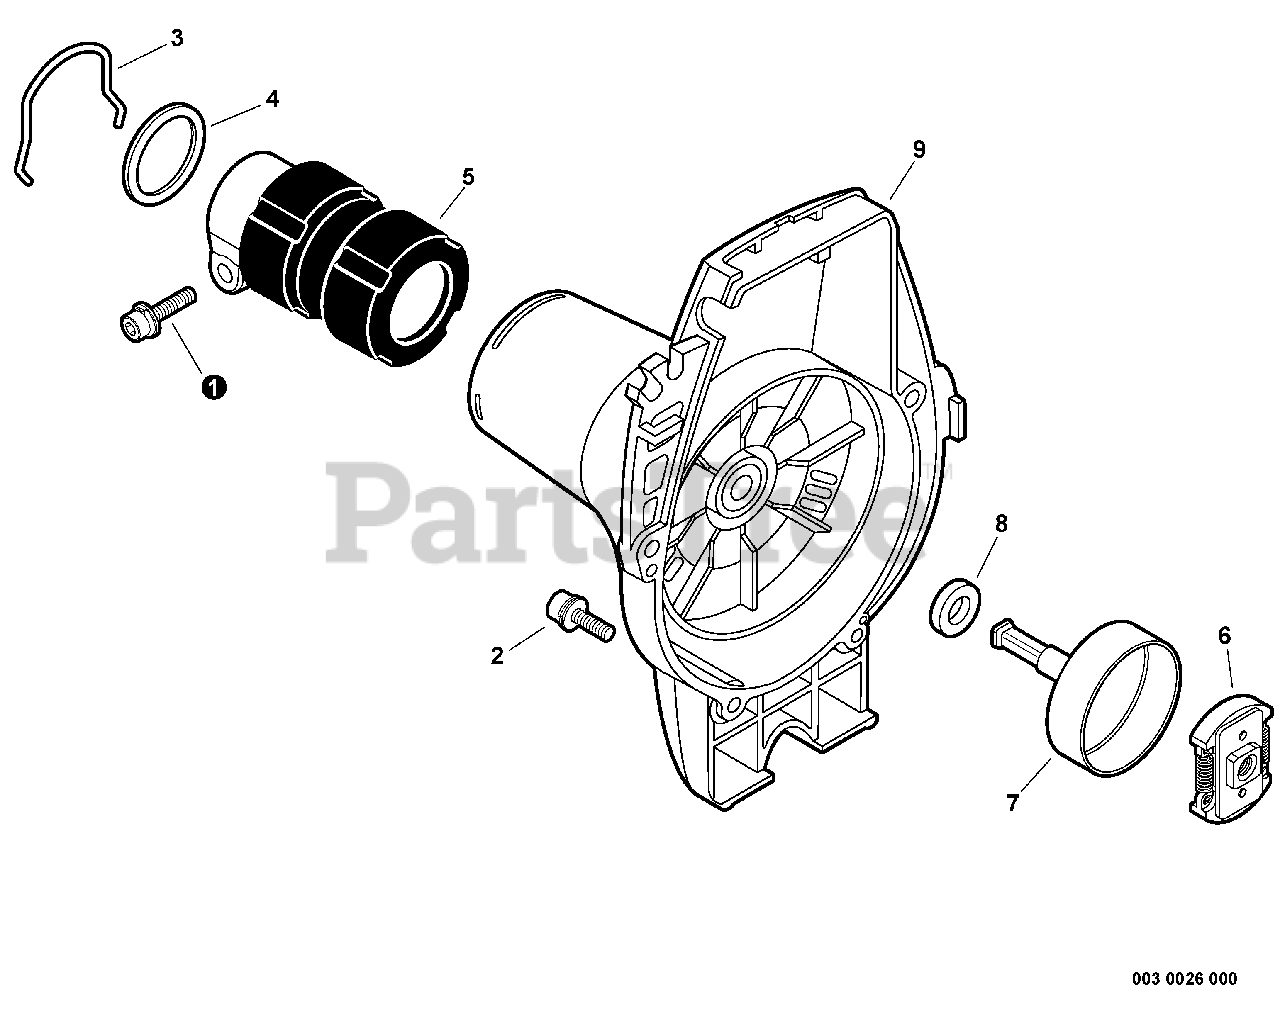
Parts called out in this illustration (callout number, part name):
1	BOLT 5×28
2	SCREW 4×16
4	WASHER 33.5×41.0×T0.5
5	HOLDER, MAIN PIPE
6	CLUTCH ASSY
7	DRUM, CLUTCH
8	PACKING, FELT
9	COVER, FAN
